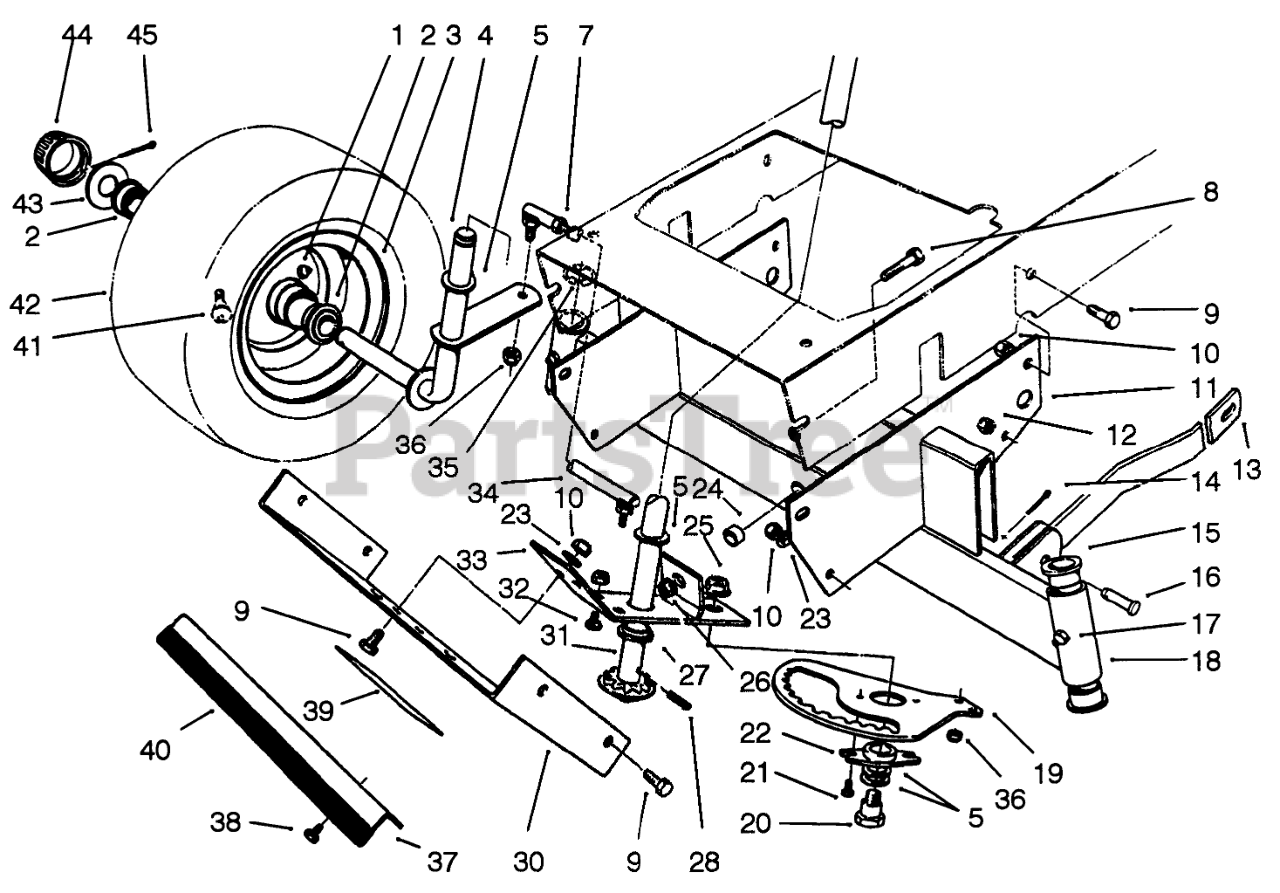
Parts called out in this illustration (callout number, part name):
1	FITTING-GREASE
2	Bearing
4	Spindle RH
5	WASHER-THRUST
7	NUT-JAM
8	SCREW-HH
9	SCREW-HH
10	NUT-LOCK, NI
11	Support
12	NUT-HEX
13	Arm-Suspension, Front
14	PIN-COTTER
15	BEARING-FLANGE
16	PIN-CLEVIS
17	GREASE FITTING
18	Axle-Front (Incl. Ref. #15 & 17)
19	Rack-Steering
21	SCREW-HWH
22	BUSHING-SECTOR
23	WASHER-PLAIN
24	SPACER-AXLE, FRONT
25	NUT-HF
26	NUT-HF
27	BEARING-FLANGE
28	PIN-ROLL, SLOTTED
30	Cover-Front
31	STRG SHAFT WA
32	SCREW-CARR
33	Bracket-Rack, Steering (Incl. Ref. #27)
34	Tie Rod-Adjustable (Incl. Ref. #7)
35	E-RING
36	NUT-LOCK
37	FRONT GUARD R
38	SCREW-HWHTF
39	Decal-Warning
40	TRIM-FRONT GUARD
41	Stem-Valve
42	TIRE,PNEU.11X4.00X5
43	WASHER-PLAIN
44	CAP-HUB
45	PIN-COTTER
